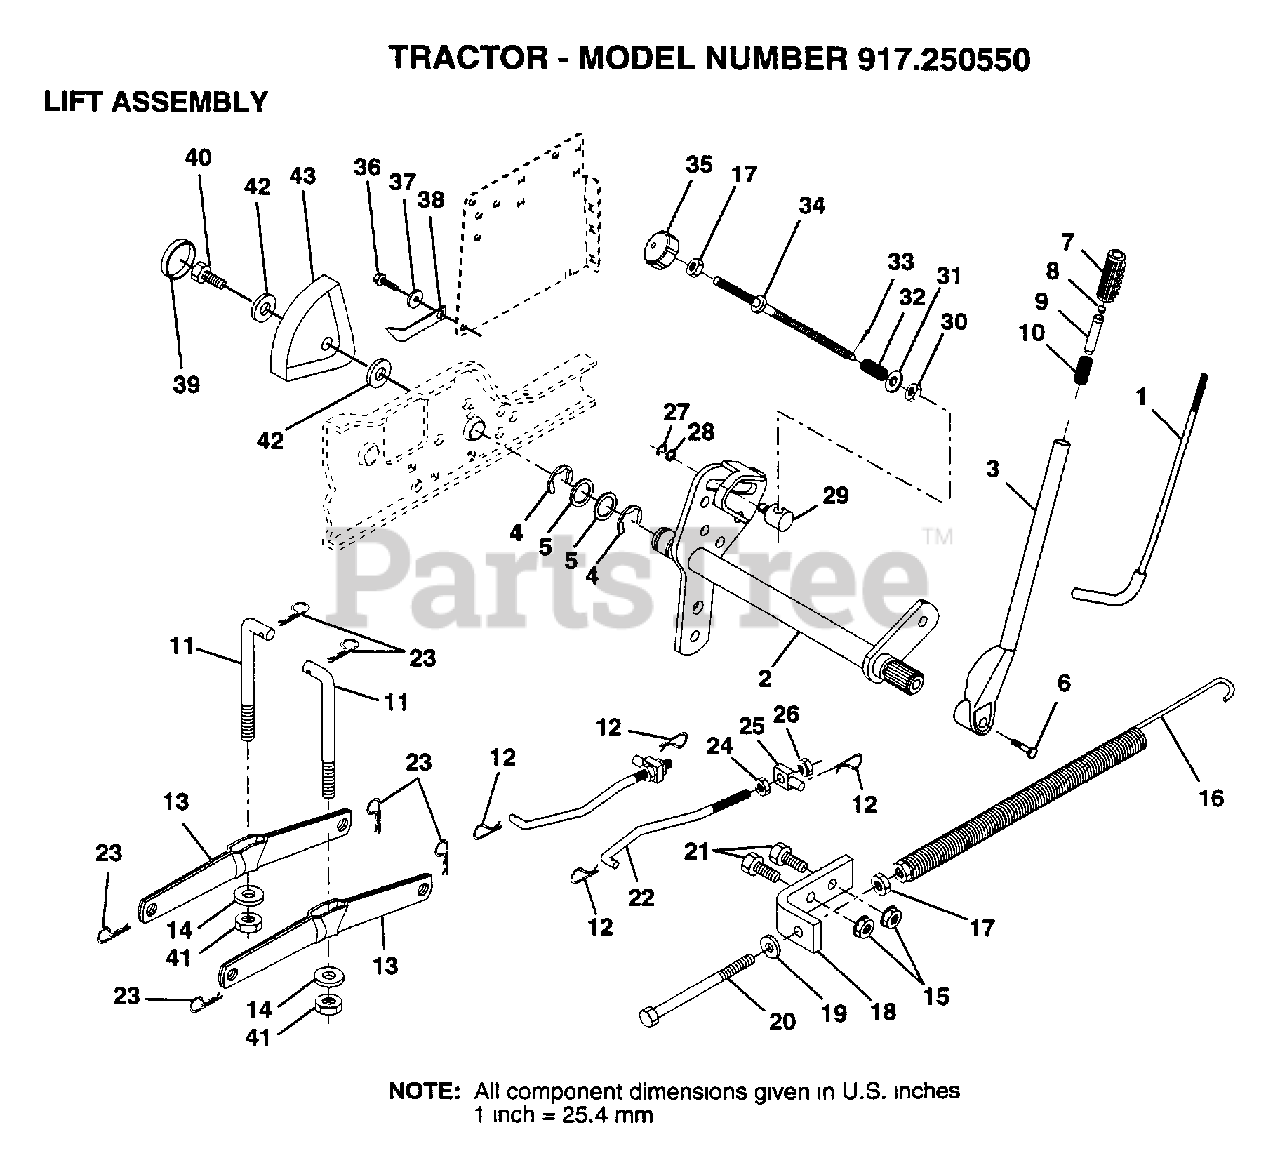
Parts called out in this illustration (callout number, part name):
1	LEVER ROD LT
2	SHAFT.LIFT.VGT.95
4	E-RING
5	WASHER
6	"BOLT,HEX"
7	GRIP HANDLE
10	SPRING T
11	LINK.LIFT.MWR.VGT
12	RETAINER.SPRING
13	ARM SUSP REAR
14	BEARING PVT LH
17	NUT
18	BRACKET SPRING AS
19	WASHER
20	BOLT-ADJ SPRING T
21	BOLT
22	LINK.FRONT
24	NUT
25	TRUNION
26	NUT.LK.W/WSH.1/2.
27	KLIP RING
28	WASHER
29	TRUNION LT
30	NUT T
31	WASHER
32	SPRING.COMP.INF.H
34	ROD.ADJ.LIFT
35	KNOB INF 3/8-16
37	WASHER T
38	POINTER HGT IND
39	"PLUG,HOLE"
40	SCREW
41	NUT.CROWNLOCK.3/8
42	WASHER
43	HEIGHT INDICATOR
